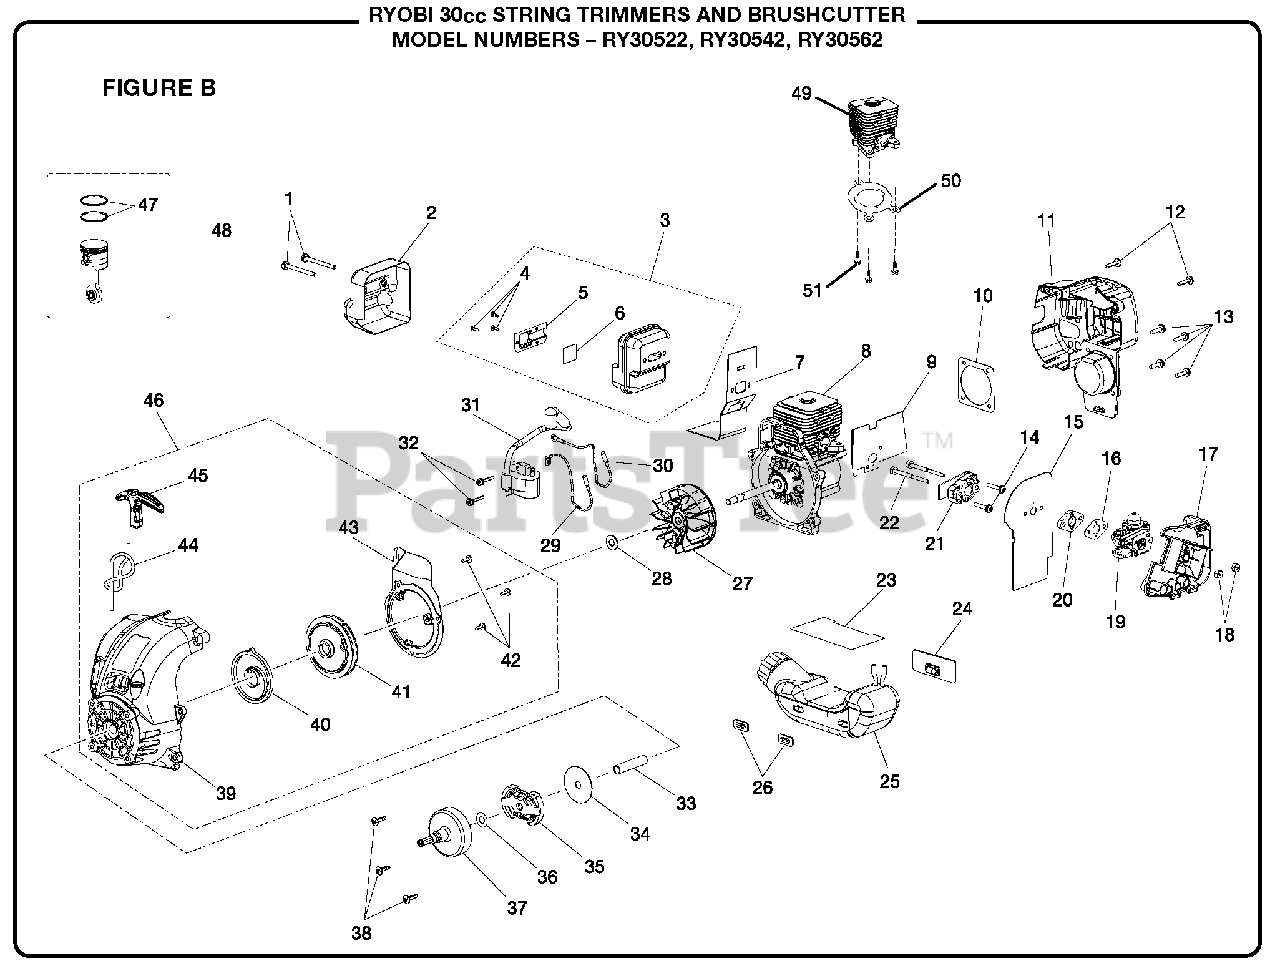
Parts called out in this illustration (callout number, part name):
1	Screw (10-x 24 x-1/8 in.Torx Tr.Hd.)
2	Heat Shield
3	Muffler Assembly
4	Screw (Recessed Pan Hd.)
5	Outlet Tube
6	Screen
7	Muffler Gasket
8	Short Block Assembly (30 cc ) (External Gaskets Not Included)
9	Intake Gasket
10	Cover Gasket
11	Rear Housing
12	Screw (10-14 x 7/8 in.Truss Hd.Tf.)
13	Screw w/Lock Washer (10-24 x 3/4 in.Pan Hd.Torx)
14	Screw (10-24 x 1 in.Pan Hd.)
15	Carburetor Gasket
16	Carburetor Gasket (Non-strato)
17	Air Filter Base
18	Lock Nut (10-24)
19	Carburetor Assembly
20	Spacer
22	Carburetor Mounting Bolt (10 x 2-1/in.)
23	Tank Insulation Gasket
24	Rubber Bumper
25	Fuel Tank Assembly w/Cap
26	Bumper
27	Rotor w/Pawls Assembly
28	Washer
29	Lead w/Terminals
30	Lead w/Terminals
31	Ignition Module w/Sec.Kill Switch
32	Screw (8-32 x 1 in.)
33	Spacer Tube
35	Clutch Assembly
36	Clutch Washer
37	Drum and Connector
38	Screw (10-24 x 3/4 in.)
39	Starter Housing and Eyelet Assembly
40	Spring and Container
41	Starter Pulley Assembly
42	Screw (8-16 x 1/in.)
43	Baffle/Isolator
44	Starter Rope (42in.)
45	Starter Grip
46	Starter Housing Assembly
47	Piston Ring
48	Piston w/Rod Assembly
49	Cylinder, 30cc
50	Cylinder Gasket
51	Screw (M5 x 20 mm)
